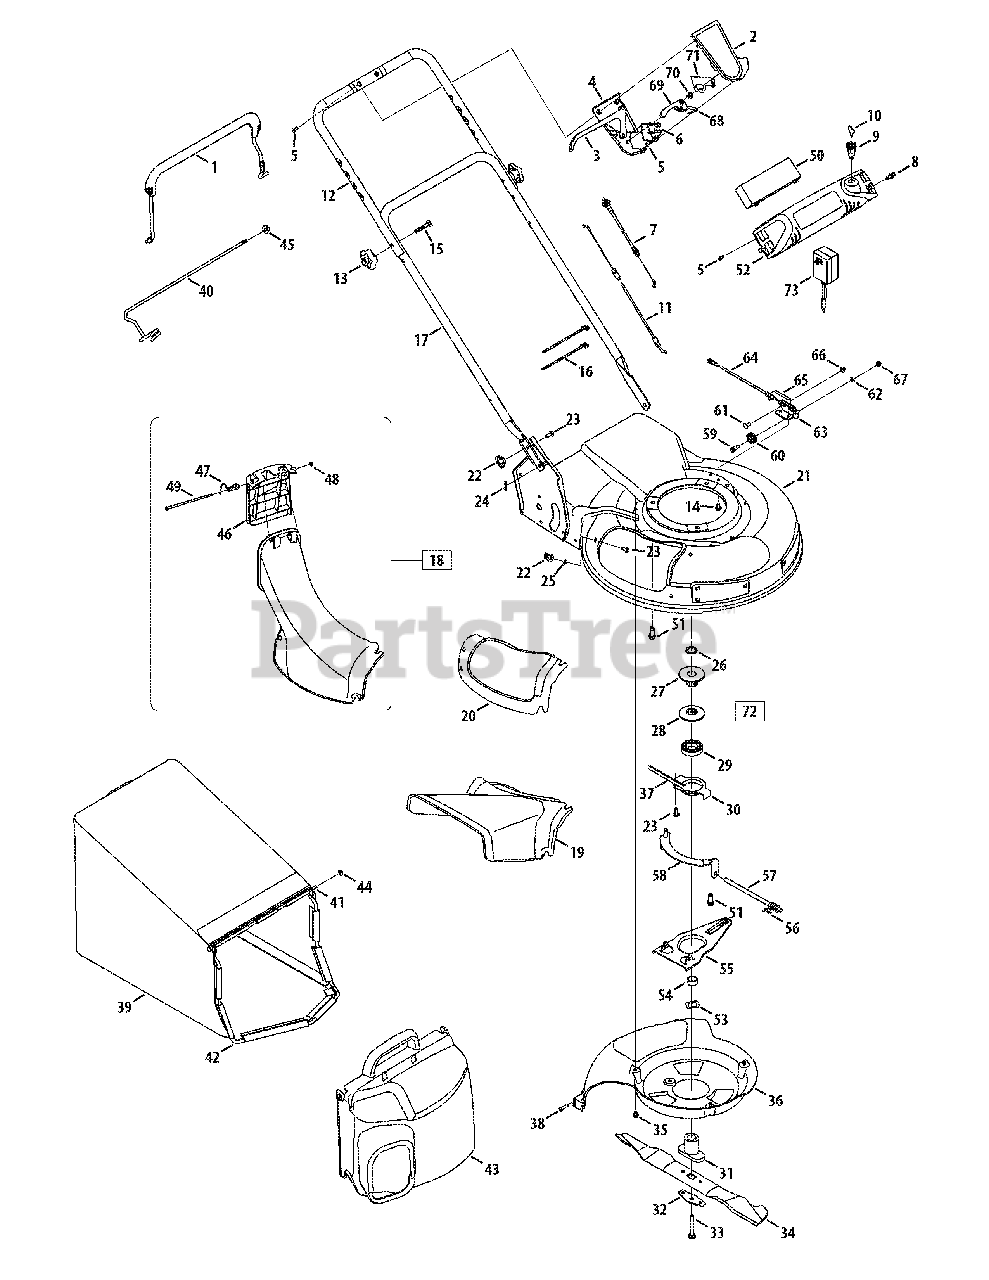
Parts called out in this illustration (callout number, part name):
1	Blade Control
2	Upper Control Housing
3	Drive Control
4	Lower Control Housing
5	C Sunk Tap Screw, #10 x.75 Lg
6	Cable Mounting Cap
7	Drive Cable
9	Key Switch
11	Control Cable
13	Star Knob
14	Screw, 1/4-20 x .625
15	Carriage Bolt, 5/16-18 x 2.0
16	Cable Tie
18	Adapter Assembly
19	Side Discharge Chute
20	Mulch Cover
22	Wing Nut
23	Carriage Bolt, 1/4-20 x .75"
24	Cotter Pin
25	Push Nut, .25 x ID x .50 OD
26	Sleeve Spacer, .88ID x 1.13OD
27	Half Pulley: 2.62 OD
28	Half Pulley: 2.62 OD x 1.61
29	Ball Bearing
31	Blade Adapter
32	Blade Bell Support
33	Hex Bolt, 3/8-24 x 2.5
34	21" Mulching Blade
35	Screw, 1/4-20 x 3.75
36	Baffle
37	Belt, 3/8 x 39.24
38	Screw, 1/4-15 x .750
39	Grass Catcher
40	Support Rod w/ Rope Guide
41	Pivot Rod
42	Grass Catcher Frame
43	Grass Catcher Cover
44	Cap Nut
45	Flange Lock Nut, 5/16-18
46	Chute Door
47	Torsion Spring
49	Pivot Rod
50	12V Battery
51	Sems Screw, 3/8-16 x 1.00
52	Harness Assembly
53	Wave Washer, 1.38 ID x.88 OD
54	Slve Spacer, .88 ID x 1.00 OD
57	Pivot Shaft
59	Shlder Screw, .375 ID x 1/4-14
60	Cable Roller
61	Carriage Screw, 1/4-20 x .62
62	Lock Washer, 1/4
63	Cable Mounting Bracket
64	6 Speed Cable
65	Cable Adjustment Bracket
66	Hex Nut 1/4-20
67	Hex Nut 1/4-28
68	Shift Lever Spring
69	6 Speed Shift Lever
70	Gear Insert
71	6 Spd. Rack Cable Bracket
72	Pulley Assembly
73	12V Battery Charger
